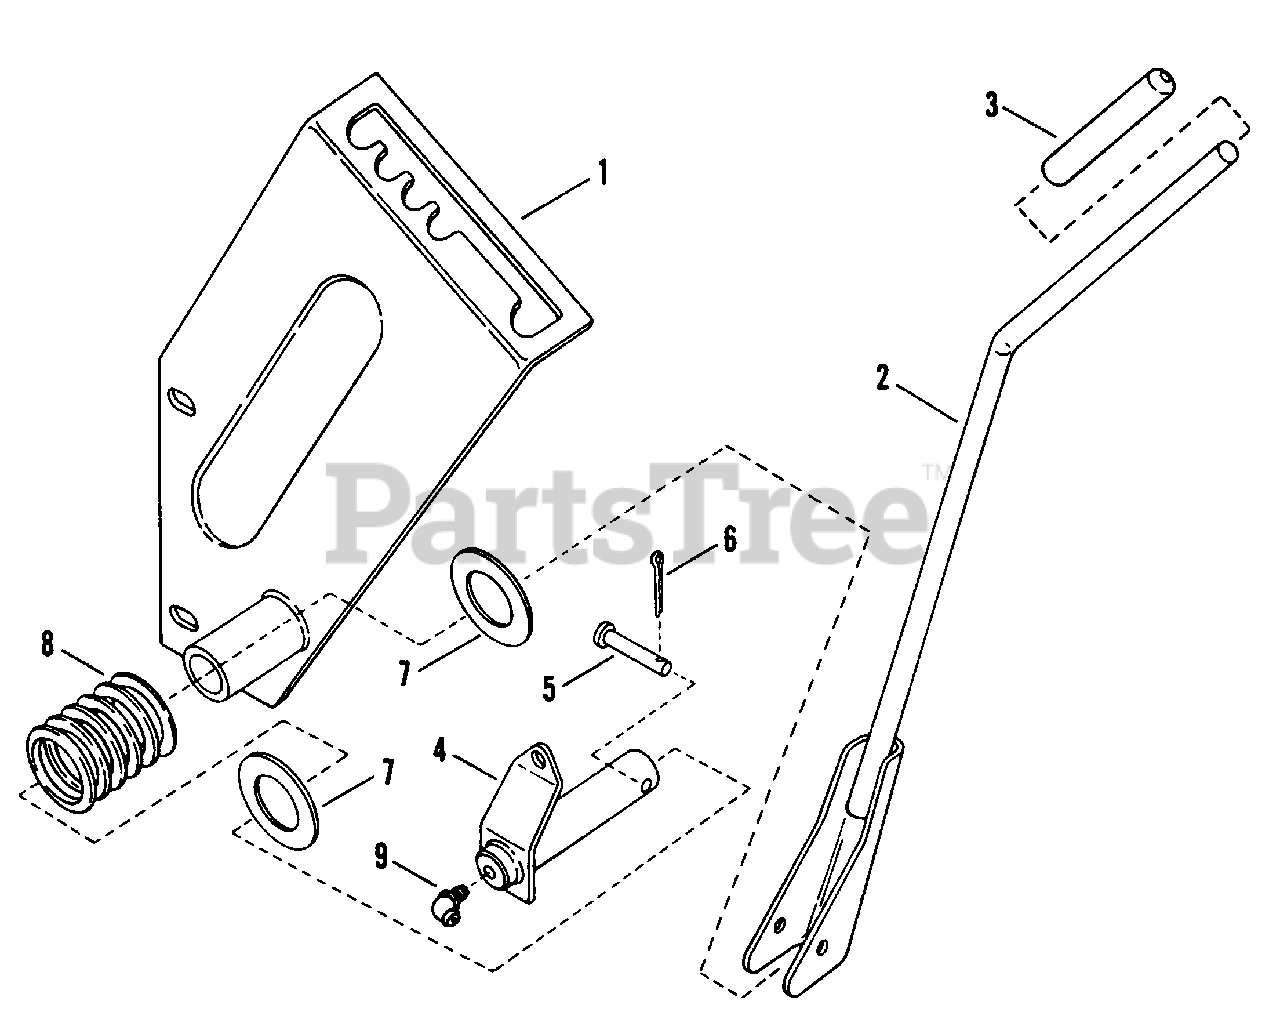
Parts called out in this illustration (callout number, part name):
1	WELDMENT, Shift Quadrant
2	HANDLE, Shift
3	GRIP, Shift Handle
4	WELDMENT, Structure
5	PIN, 1/4 x 1-1/4" Clevis
6	PIN, 3/32 x 3/4" Cotter
7	WASHER, Thrust
8	SPRING, Tension
9	FITTING, Grease
